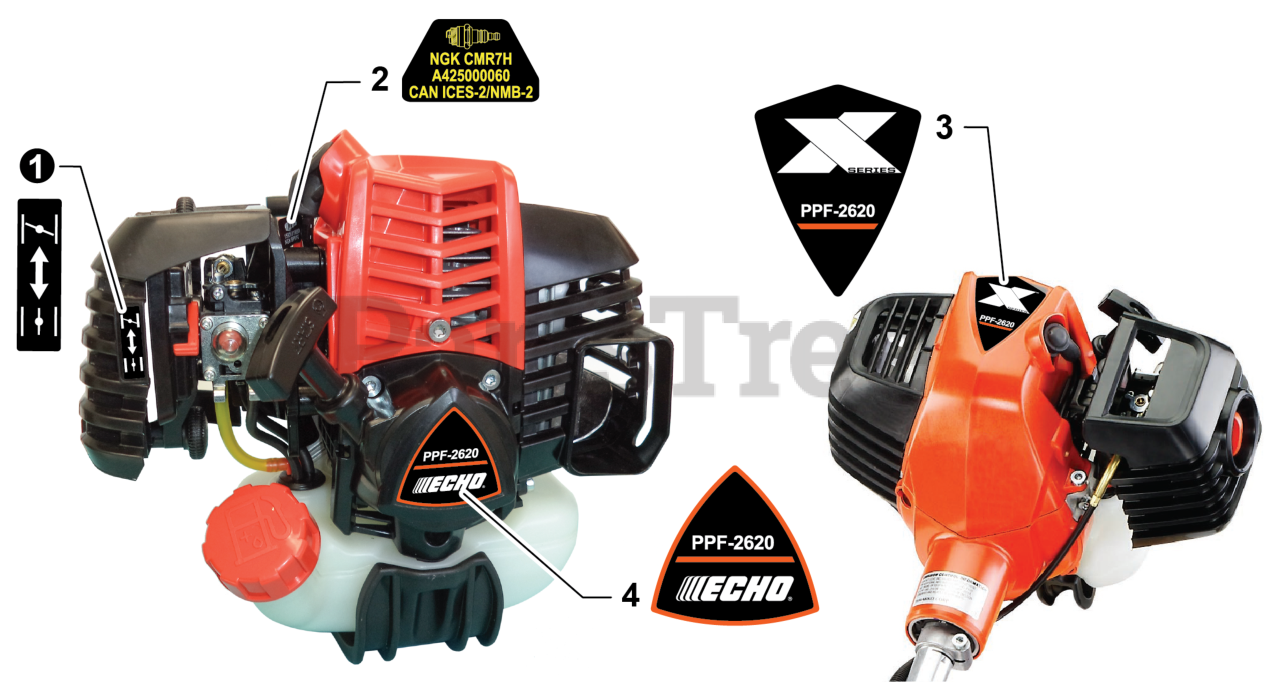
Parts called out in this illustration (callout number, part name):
1	LABEL - CHOKE
2	LABEL - SPARK PLUG - CMR7H
3	LABEL - MODEL PPF-2620
4	LABEL - RECOIL STARTER - PPF-2620
